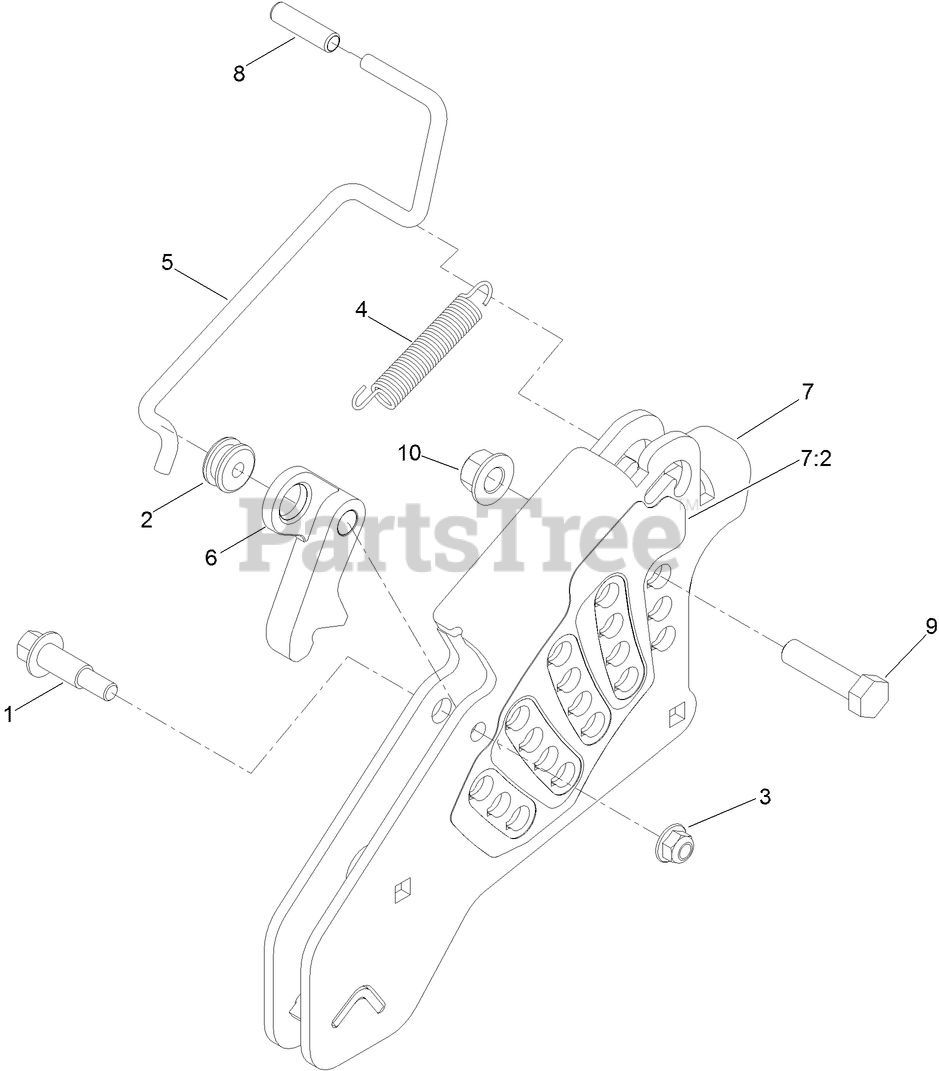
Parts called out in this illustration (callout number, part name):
1	BOLT-SHOULDER
2	GROMMET
3	NUT-HF, NI
4	SPRING-EXTENSION
5	ROD-LOCK, TRANSPORT
6	PAWL-TRANSPORT, HOC
7	HOC PLATE W/DECAL ASM
7:2	DECAL-HOC
8	GRIP-LEVER
9	SCREW-HH
10	NUT-LOCK
